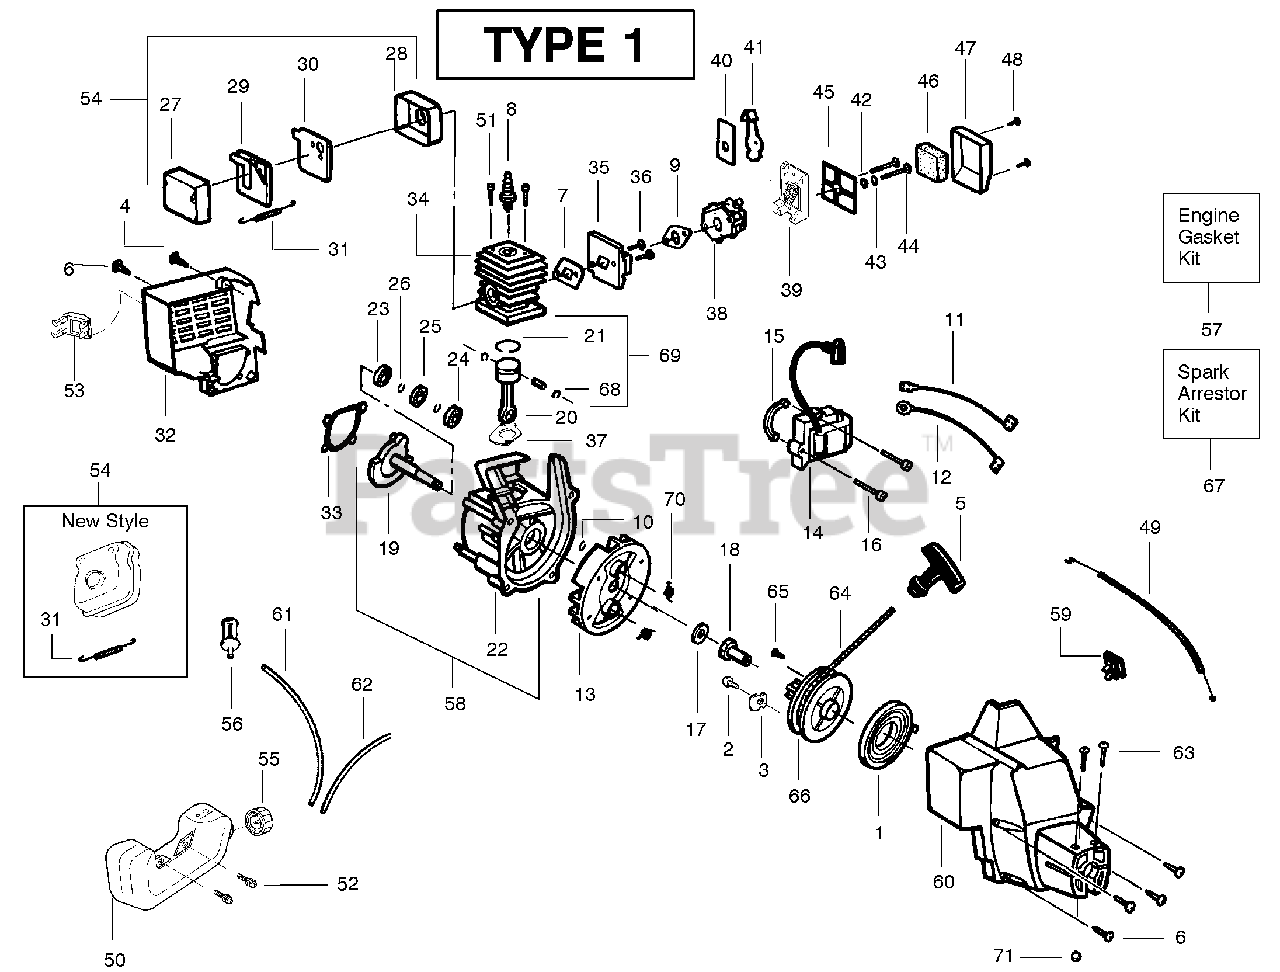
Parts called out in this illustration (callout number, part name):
1	Starter Spring
2	Screw Pulley
3	Retainer Pulley
4	Screw Shrd/Fan Hsg.
5	Starter Handle
6	Screw
7	Gasket Cylind./Carb.
8	Spark Plug (RCJ 8Y)
9	Gasket Carb.
10	Retainer Ring C'shaft
11	Lead Wire Ass'y.
12	Ground Wire Ass'y.
13	Flywheel Ass'y.
14	Ignition Module
15	Spacer Ignit. Module
16	Screw Ignit. Module
17	Washer Flat
18	Drive Coupling
19	Crankshaft Ass'y.
20	Connecting Rod Ass'y.
21	Piston Ring
22	Crankcase Ass'y.
23	Inner Bearing
24	Outer Bearing
25	C'case Seal
26	Retain. Ring C'case
27	Muffler Body
28	Muffler Cover
29	Muffler Baffle - Exit
30	Muffler Baffle - First
31	Muffler Spring - Old Style
31	Muffler Spring - New Style
32	Rear Shroud
33	Gasket C'case
34	Cylinder Kit
35	Carb. Adapter
36	Screw Carb Adaptor
37	Gasket Cylinder
38	Carburetor Ass'y. Kit Walbro (WA226)
38	Carburetor Ass'y. Kit Zama (C1U-W7)
40	Choke Plate
41	Choke Shutter
43	Choke Spacer
45	Filter Plate
46	Air Filter Foam
47	Air Filter Cover
48	Screw Air Box
49	Throttle Cable Ass'y.
50	Fuel Tank Ass'y
51	Screw Cylinder
52	Retainer Fuel Tank
53	Guard Muffler
54	Muffler Kit - Old Style
54	Muffler Kit - New Style
55	Fuel Cap Ass'y.
56	Fuel Pickup Ass'y.
57	Engine Gasket Kit
58	C'case & C'shaft Assy.
59	On/Off Switch
60	Fan Housing Ass'y
61	Fuel Line Carb./Purge
62	Fuel Line Tank/Purge
64	Rope Kit
65	Screw Rope Retain.
66	Starter Pulley Kit
67	Spark Arrestor Kit - Old Style
67	Spark Arrestor Kit - New Style
68	Piston Pin Retainer
69	Piston Kit
70	Starter Dog Spring
